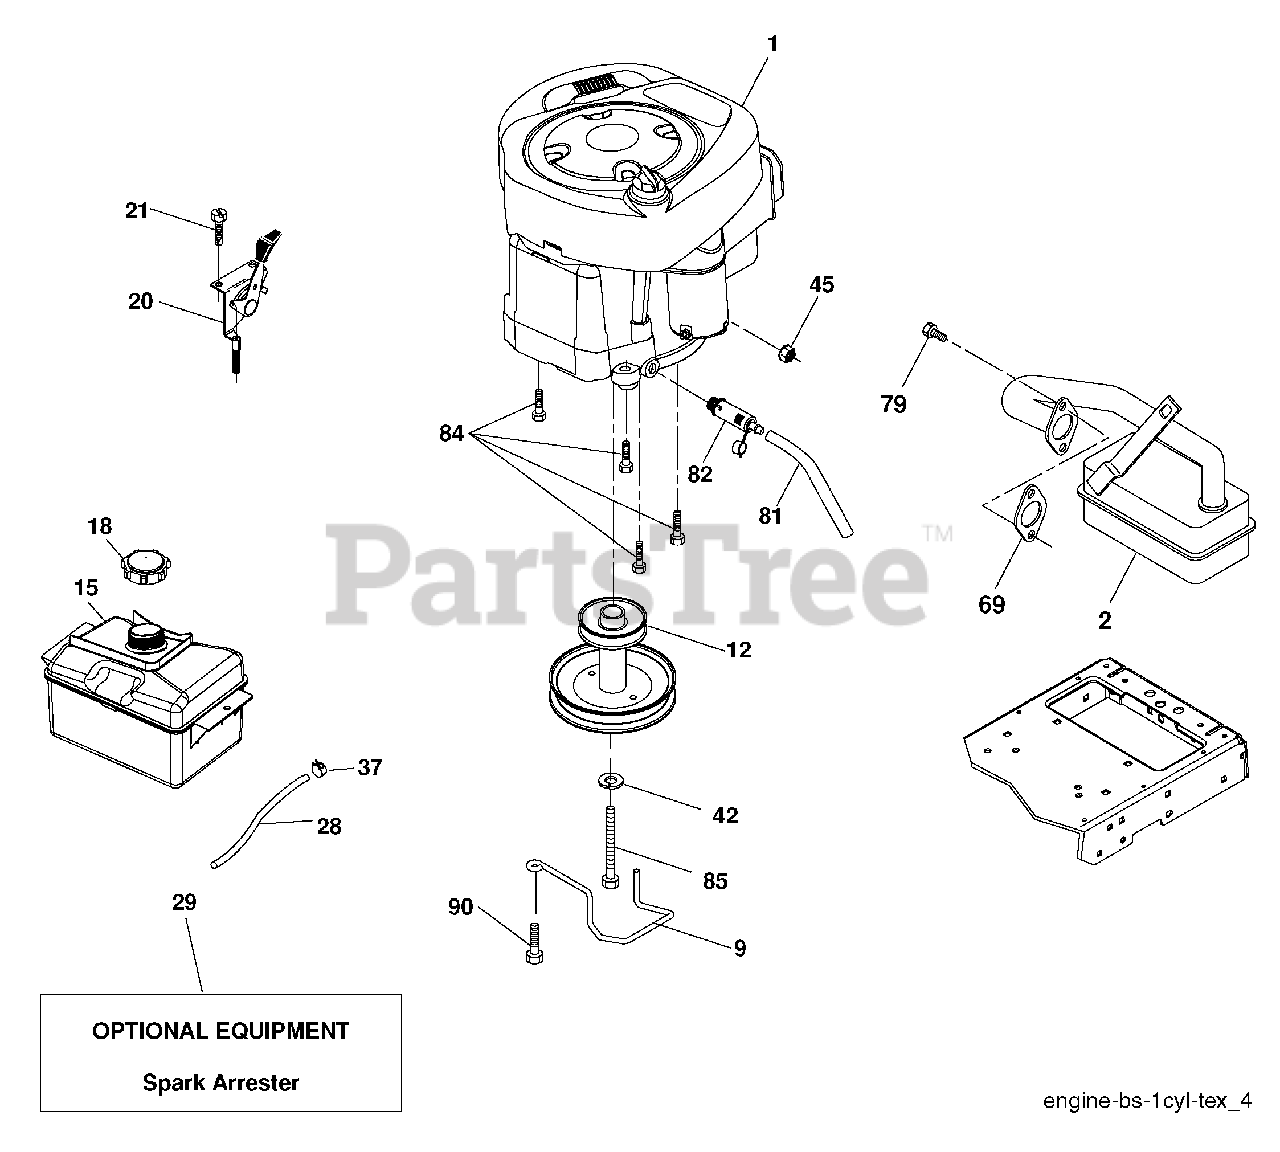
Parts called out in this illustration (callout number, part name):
2	Muffler
9	Keeper Belt Engine
12	Pulley Engine
15	Tank Fuel 1.50
18	Cap Asm
20	Control Throttle/Choke
21	Screw 10 x 3/4 Single Lead-Hex
28	Fuel Line
29	Spark Arrester Kit
37	Clamp Hose
42	Washer Lock 7/16
45	Nut Keps Hex 1/4-20 unc
69	Gasket
79	Screw Socket Hd 5/16-18 x .75
81	Tube Drain Oil Easy
82	Plug Drain Oil
84	Screw 3/8-16 x 1-1/4
85	Bolt Hex 7/16-20 x 4 x Gr. 5-1.5
90	Screw 3/8-16 x 1.0
